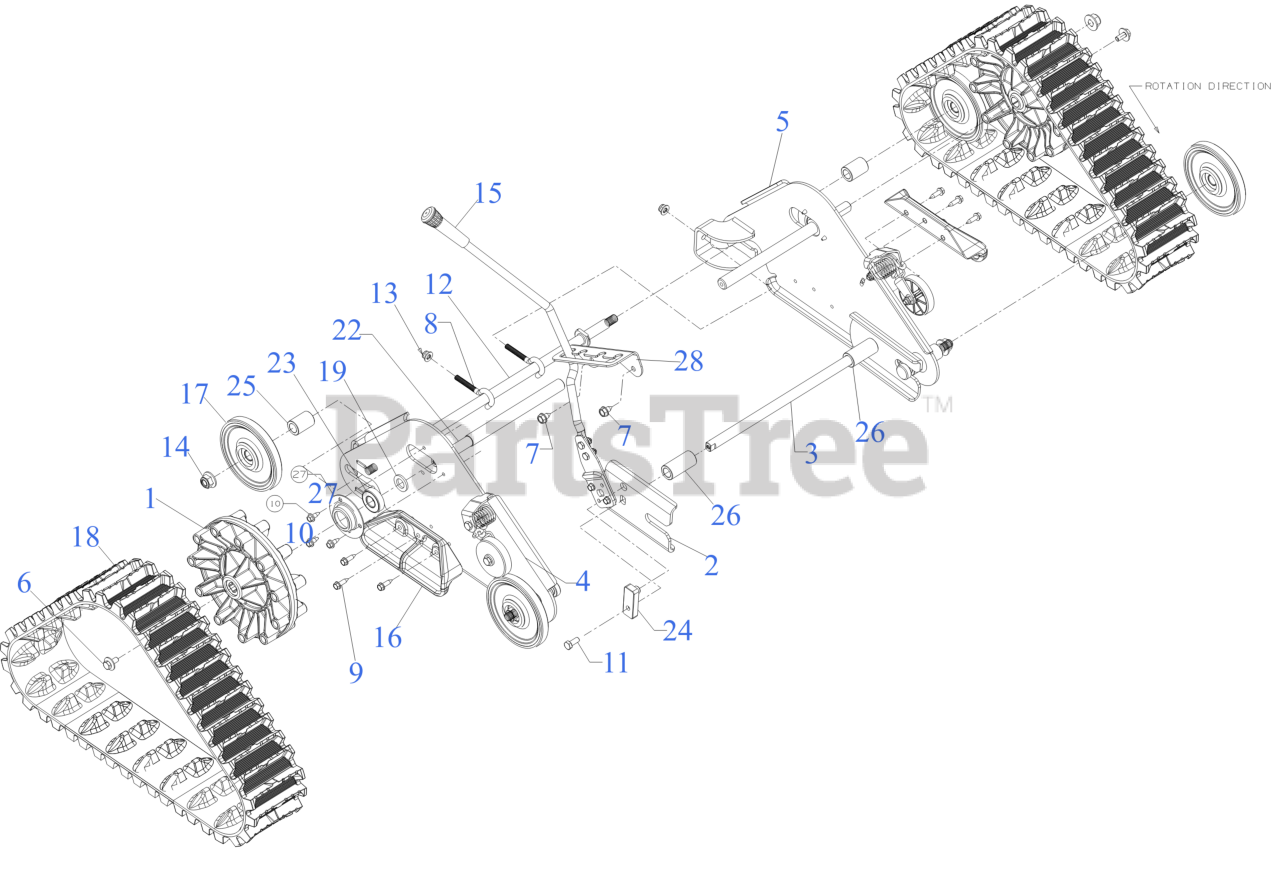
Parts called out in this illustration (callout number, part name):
1	TRACK DRIVE WHEEL
2	HEIGHT ADJUSTMENT LEVER ASSEMBLY
3	HEIGHT ADJUSTMENT ROD ASSEMBLY
4	TRACK ASSEMBLY (RH/FRT)
5	TRACK ASSEMBLY (LH/FRT)
6	SCREW 5/16-24 x .750 GR5
7	SCREW 5/16-18 x .625
8	EYE BOLT 5/16-18 x 2.675
9	SCREW-TT 1/4-20 x .875
10	SCREW 1/4-20X.625
11	SCREW 5/16-18 x .750
12	REAR WHEEL AXLE
13	FLANGE LOCK NUT 5/16-18
16	TRACK SKID
17	WHEEL-5.00 OD BB
18	DRIVE TRACK 61MM x 22 PITCHES
19	FLAT WASHER
22	AXLE-.75 OD x 11.06 LG
23	BALL BEARING
24	HEIGHT ADJUSTMENT ADAPTER
27	BEARING CUP
28	HEIGHT ADJUSTMENT BRACKET
